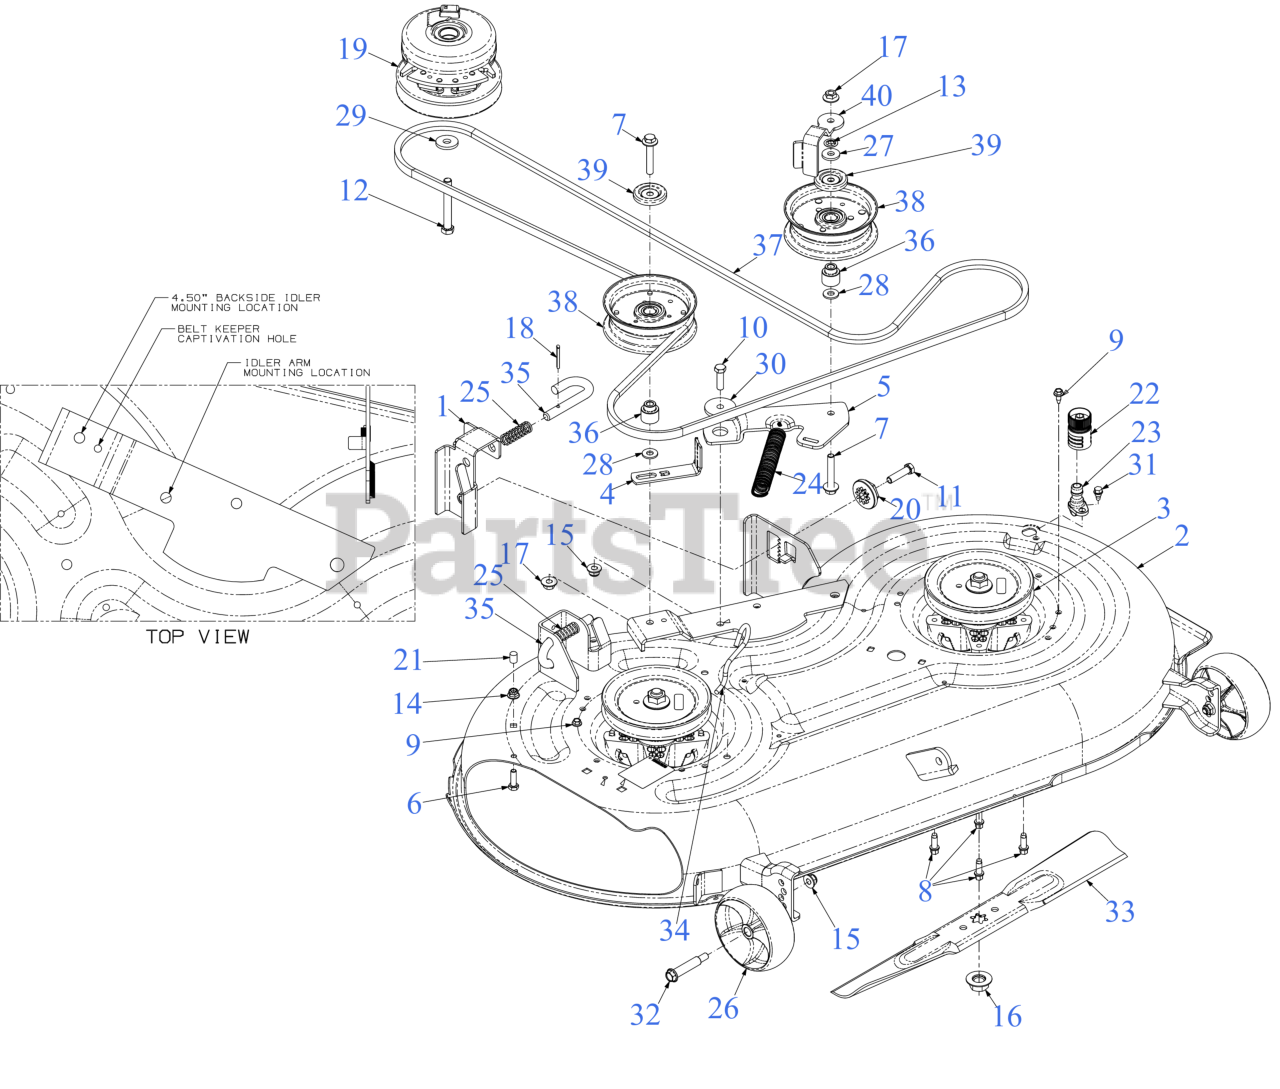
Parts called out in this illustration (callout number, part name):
2	42" DECK SHELL
3	SPINDLE ASSEMBLY
5	42" IDLER PIVOT BRACKET
6	SCREW 5/16-18 x 1.0 GR5
7	SCREW 3/8-16 x 2.25 GR5
8	SCREW 5/16-18 x .875
9	SCREW 1/4-20X.625
10	SCREW 3/8-16 x 1.25 GR5
11	SCREW 3/8-16X1.5 GR5
12	SCREW 7/16-20 x 3.25 GR5
14	FLANGE LOCK NUT 5/16-18
17	FLANGE LOCK NUT
18	COTTER PIN-5/32 DIA
19	ELECTRIC PTO CLUTCH
20	DECK ADJUSTMENT GEAR
22	WATER NOZZLE ADAPTER
23	DECK WASH NOZZLE
24	EXTENSION SPRING .94 x 6.75 RZT
25	COMPRESSION SPRING .66 OD x 1
26	DECK WHEEL (5.0 DIA x 1.875)
27	FLAT WASHER .385 x 1.00 x .135
28	FLAT WASHER .385X.870X.090
29	FLAT WASHER .445 x 1.248 x .170
30	SHOULDER SPACER
31	SHOULDER SCREW 1/4-20 x .50
32	SHOULDER BOLT (.50 X 2.0 x 3/8 -16)
33	21.23" BLADE (2N1)
33	Cub Cadet 42" BLADE SET
33	Genuine Factory Parts 42" BLADE SET(2N1)
33	Troy-Bilt 42" BLADE SET(2N1)
33	21.23" BLADE (2N1) (XTREME)
33	Cub Cadet BLADE SET (XTREME)
33	BLD:XTREME SET MTD
33	42" 6 PT STAR LOW LIFT/SAND BLADE
33	21.33" BLADE (HI-LIFT)
33	21.23" BLADE (MULCH)
34	DECK SPRING HOOK
35	DECK RELEASE PIN
36	SHOULDER SPACER
37	BELT A SEC x 114.24"
37	Cub Cadet 42"RZT DECK BELT (04317)
37	Genuine Factory Parts 42" DECK DRIVE (954-04137A)
38	IDLER PULLEY 4.50" DIA
39	IDLER PULLEY CAP
40	BELT KEEPER
